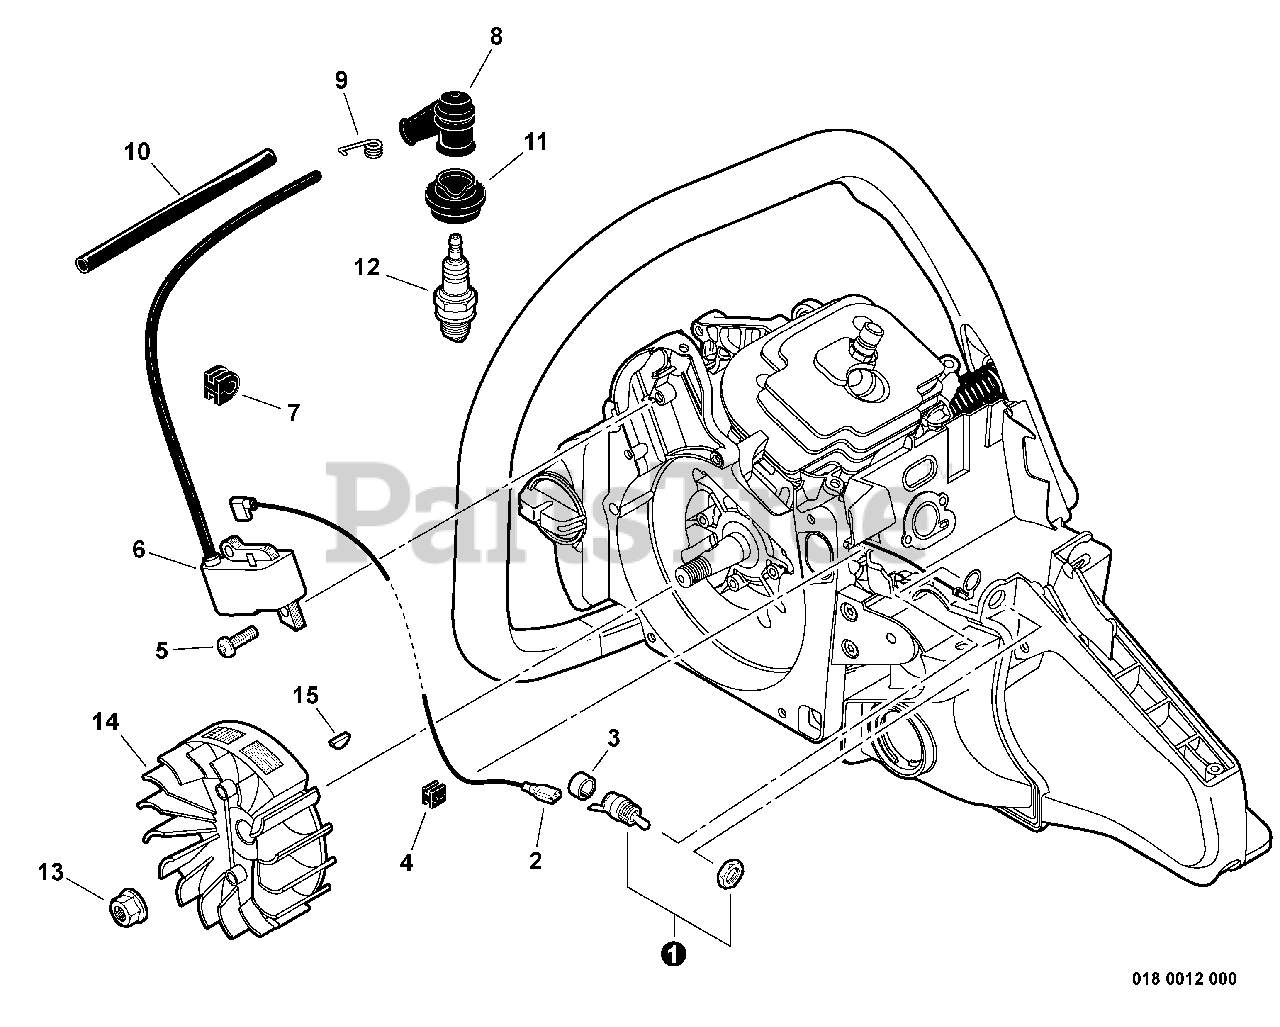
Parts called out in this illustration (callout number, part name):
1	IGNITION SWITCH KIT
2	LEAD - IGNITION
3	CAP, SPARK PLUG
5	SCREW - 5X16
6	COIL, IGNITION
8	CAP, SPARK PLUG
9	TERMINAL, SPARK PLUG CAP
11	SEAL, SPARK PLUG
12	SPARK PLUG -- BPM-8Y
12	SPARK PLUG -- BPMR-8Y
13	NUT - 8 -- FLANGE
14	FLYWHEEL
